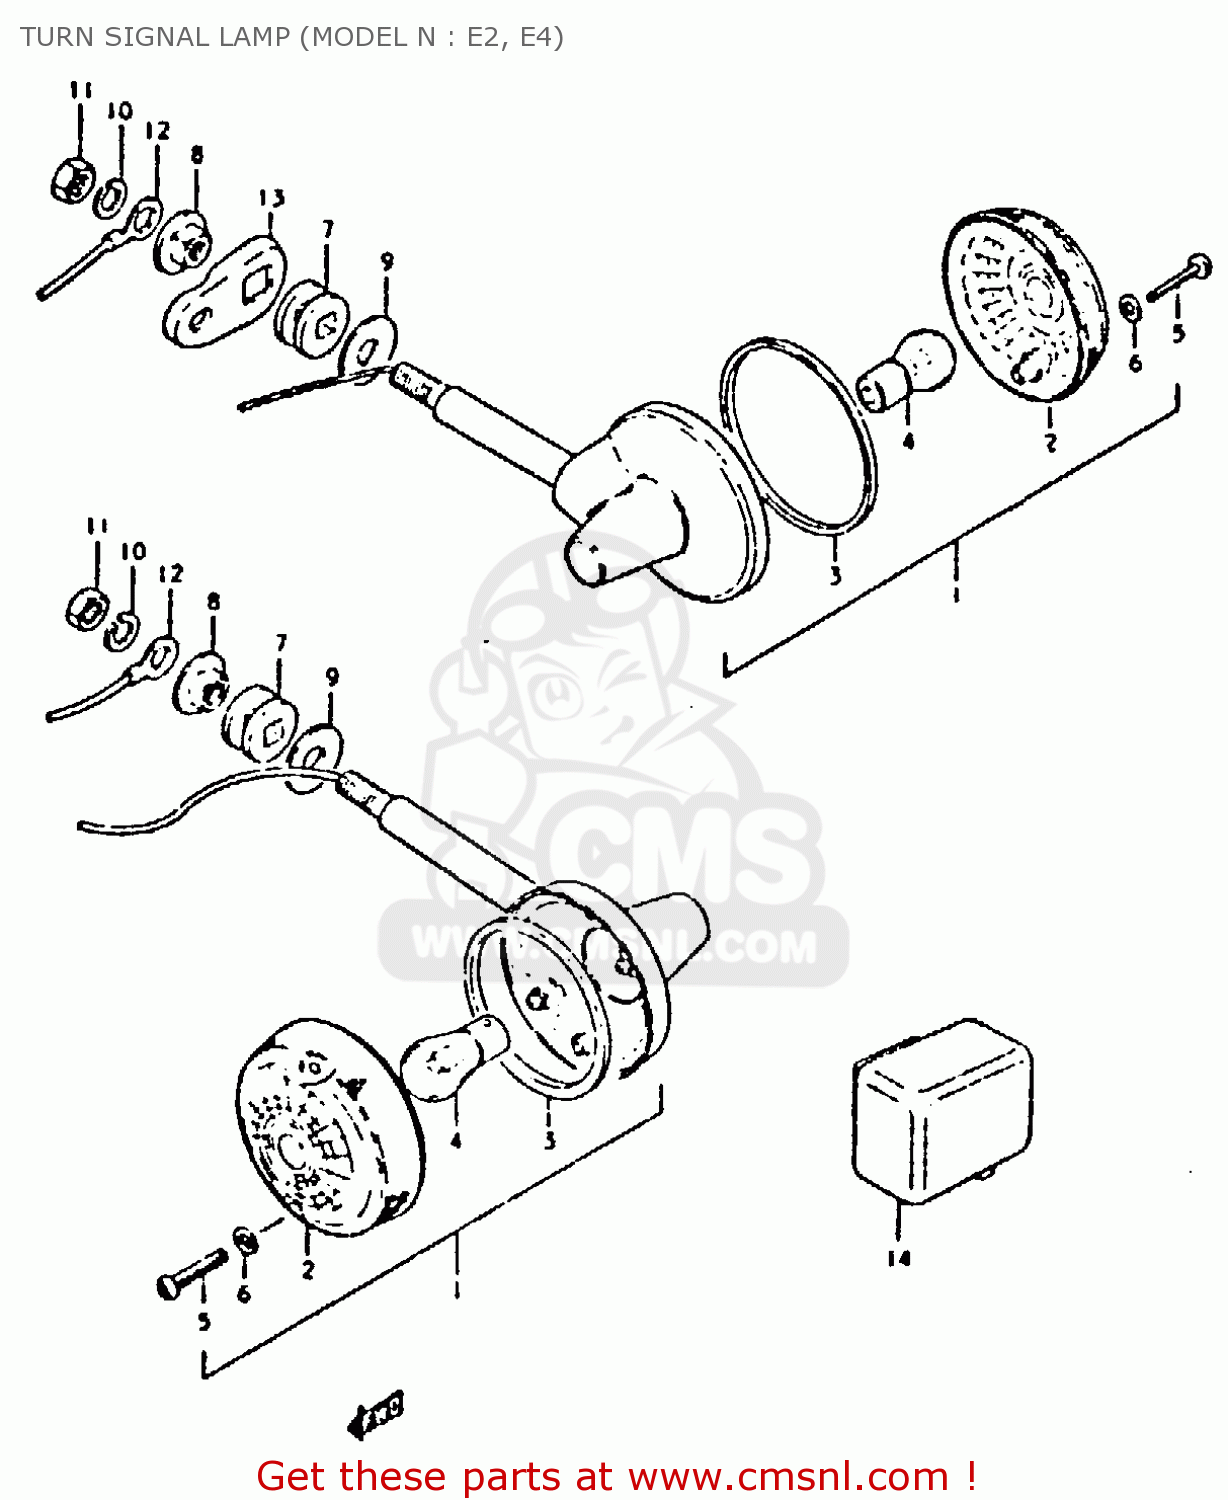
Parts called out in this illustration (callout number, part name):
1	LAMP ASSY, TURN SIGNAL
2	LENS
3	GASKET (NAS)
4	BULB 12V 21W
5	SCREW
6	GASKET (NAS)
7	CUSHION
8	SPACER,RR TURNSIGNAL LAMP
9	WASHER
10	LOCK WASHER
11	NUT
12	LEAD WIRE,EARTH
13	BRACKET,TURN SIGNAL
14	RELAY,TURN SIGNAL
